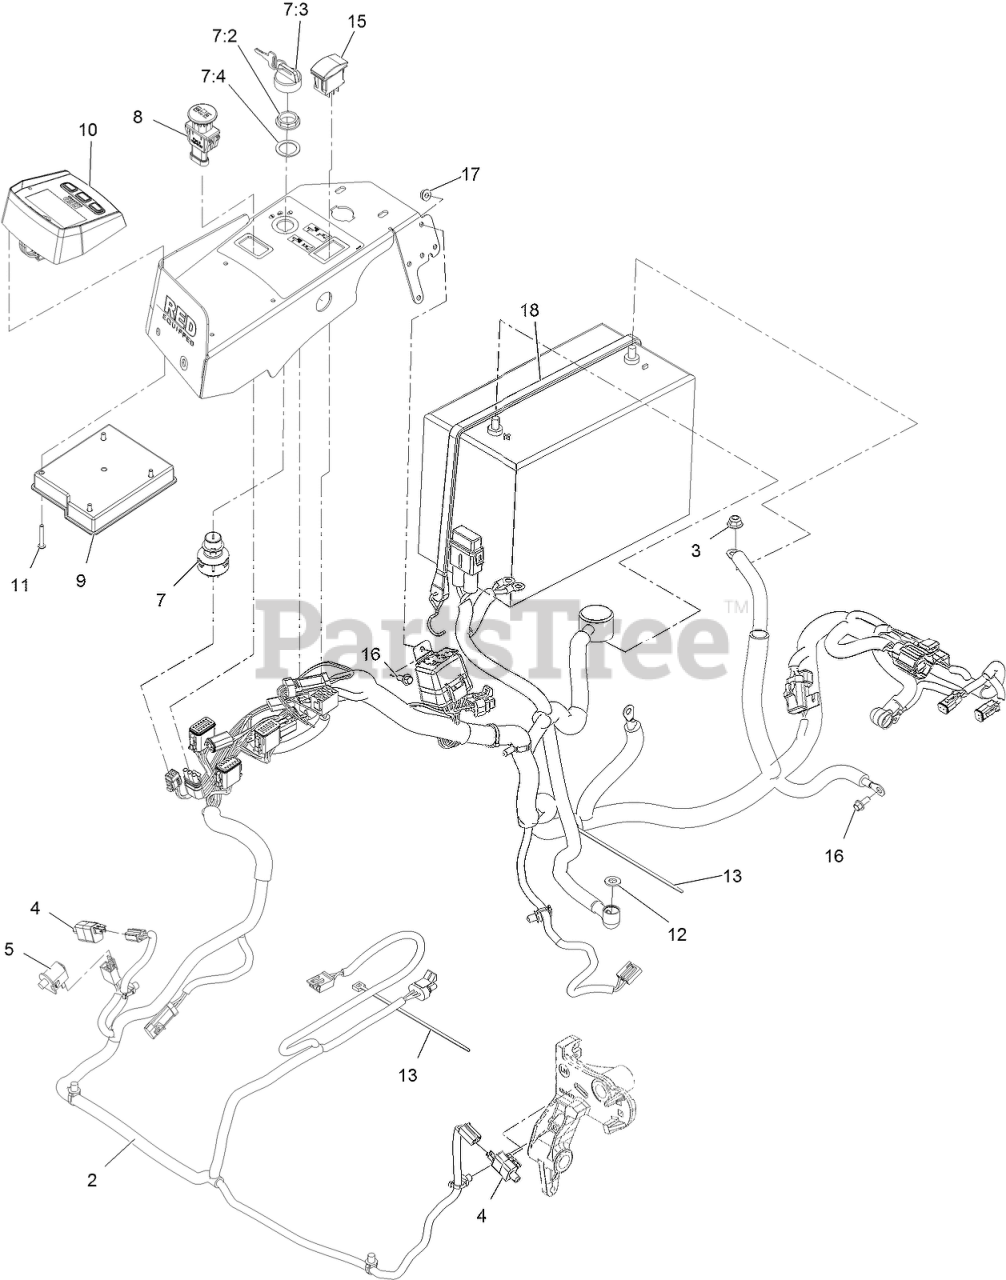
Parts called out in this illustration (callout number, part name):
2	Harness-Wire
3	NUT-HF, NI
5	SWITCH-BAIL
7	IGNITION SWITCH ASM
7:1	Switch-Ignition
7:2	NUT-MOUNTING
7:3	IGNITION KEY SET
7:4	WASHER-BACKUP
8	SWITCH-PTO, SEALED
9	Module-Mcu
10	MODULE, LDU
11	SCREW-PPH
12	WASHER-FLAT
13	TIE-CABLE
16	SCREW-HHF
